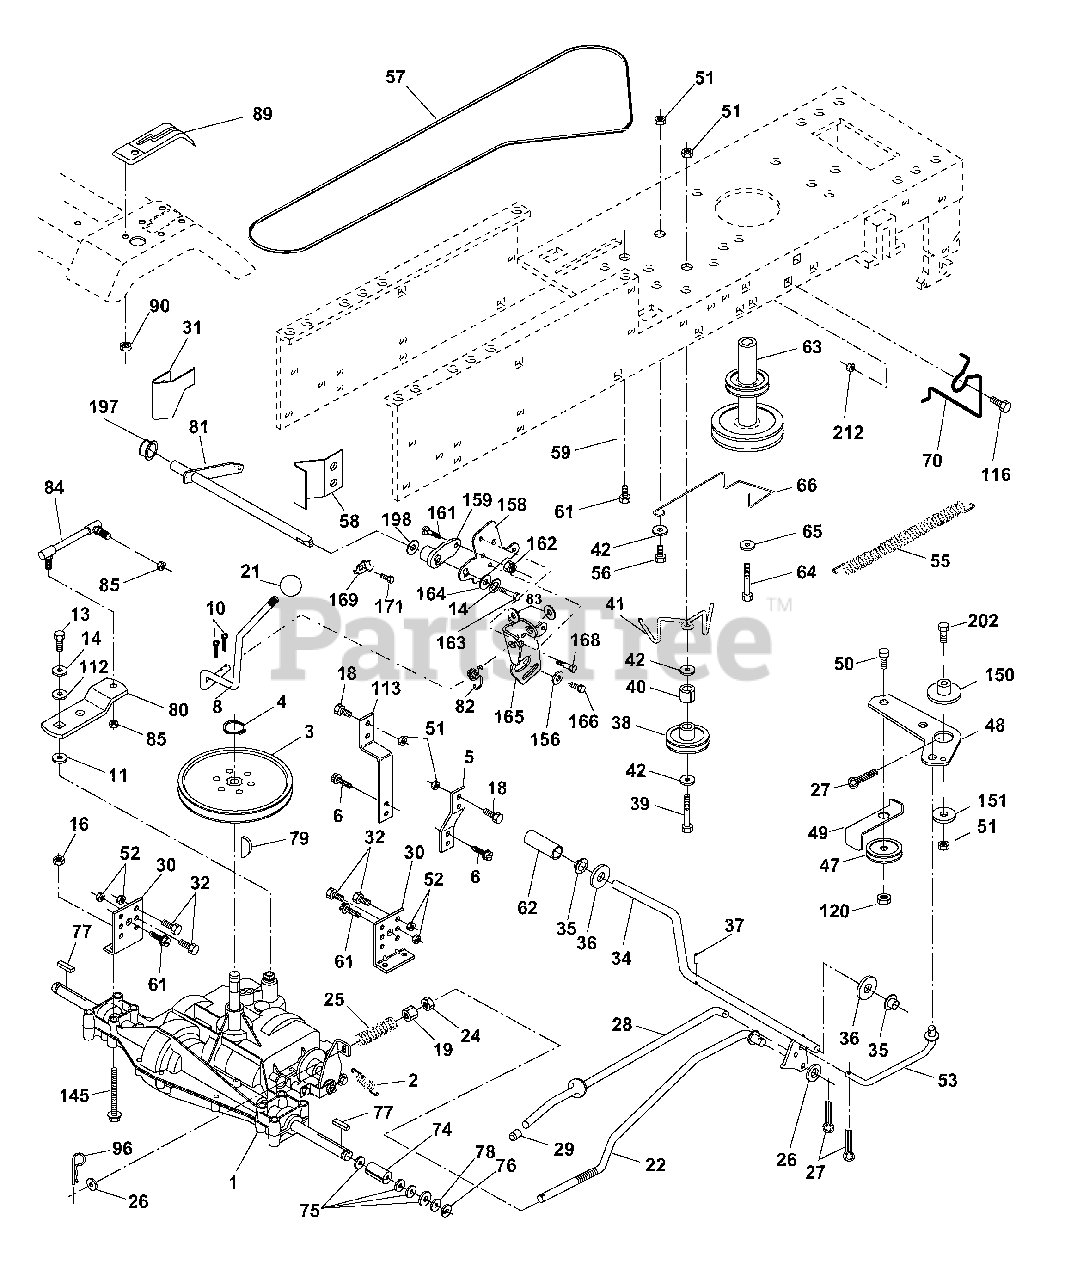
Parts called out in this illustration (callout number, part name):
1	Transaxle
2	Spring Return Brake T/a Zinc
3	Pulley Transaxle 18" tires
4	Ring Retainer # 5100-62
5	Strap Torque 30 Degrees
6	Screw 5/16-18 x 3/4
8	Rod Shifter Fender Adj Lt
10	Pin Cotter 1/8 x 1 Cad
11	Washer Plate Shf 388 Sq Hole
13	Bolt 1/4-28 Unf Gr 8 W/Patch
14	Washer Lock Hvy Helical 1/4
16	Nut Lock
18	Bolt, Fin Hex 3/8-16 UNC x 1 Gr. 5
19	Nut Lock 3/8-16 Unc
21	Knob
22	Rod Brake Blk Zinc 26 840
24	Nut Hex Jam 3/8-16 Unc
25	Spring Rod Brake 2 00 Zinc
26	Washer 13/32 X 13/16 X 16 Ga
27	Pin Cotter 1/8 X 3/4 Cad
28	Rod Brake Parking LT/YT
29	Cap Brake Parking
30	Bracket Mtg Transaxle
31	Keeper Belt LH LT 14 Ga
32	Bolt Hex Hd 5/16-18unc X 3/4
34	Shaft Asm Pedal Foot
35	Bearing Nylon Blk 629 Id
36	Washer 21/32 X 1 X 16 Ga
37	Pin Roll 3/16 X 1"
38	Pulley Idler Flat
39	Bolt Fin Hex 3/8-16unc X 2-3/4
40	Spacer Split 395 X 59 Bzp
41	Keeper Belt Retainer Idler
42	Washer 13/32 X 13/16 X 12 Ga
47	Pulley Idler V Groove Plastic
48	Bellcrank Asm
49	Retainer Belt Style Spring
50	Bolt Hex Hd 3/8-16unc X 1-1/2
51	Nut Crownlock 3/8-16 Unc
52	Nut Crownlock 5/16-18 Unc
53	Link Clutch
55	Spring Return Clutch 6 75
56	Bolt Fin Hx 3/8-16 X 1-1/4
57	V-Belt Ground Drive
58	Keeper Belt RH LT Pnt/zinc 16g
59	Keeper Belt Span Ctr
61	Screw 3/8-16 x 3/4
62	Cover Pedal Blk Round
63	Engine Pulley LT/YT
64	Bolt Hex
65	Washer Lock Hvy Hlcl Spr 7/16
66	Keeper Belt Engine Foolproof
70	Guide Belt Mower Drive RH
74	Spacer Axle
75	Washer 25/32 X 1 1/4 X 16 Ga
76	E-ring #5133-75
77	Key Square 2 0 X 1845/ 1865
78	Washer 25/32 X 1-5/8 X 16 Ga
79	Key Woodruff
80	Arm Shift
81	Shaft Asm Cross Tapered 20"t
82	Spring Torsion T/a
83	Washer 17/32 X 3/4 X 16 Ga
84	Link Transaxle
85	Nut Lock Center 1/4 - 28 FNTHD
90	Nut Self-thd Wsh-hd 1/4 Zinc
96	Retainer Spring
112	Washer 9/32 x 3/4 x 10 Ga.
113	Strap Torque Lh
116	Bolt Rdhd Sq Neck 3/8-16 x 1
120	Nut Lock 3/8-16
145	Bolt Hex 5/16-18 Gr. 5
150	Bushing Bellcrank Grd. Drive
151	Washer 13/32 x 2 x 10
156	Washer Srrted 5/16 ID x 1.125
158	Bracket Shift Mount
159	Hub Tapered Flange Shift lt
161	Bolt Rdhd Sqnk 1/4-20 x 3/4 Gr 5
162	Nut Crownlock 1/4-20 Unc
163	Bolt Hex Fin 1/4-20 Unc x 1 Gr 5
164	Washer 5/8 x .281 x 10 Ga
165	Bracket Pivot Lever
166	Screw 5/16-18 x 5/8
168	Bolt Shoulder 5/16-18 x .561
169	Plate Fastening Lt
171	Screw Thdrol 3/8-16 x 1/2
197	Nyliner, Snap - in
198	Washer, Nyl.
202	Bolt, Carriage 3/8 - 16 x 1
212	Nut Hex Flange Lock
